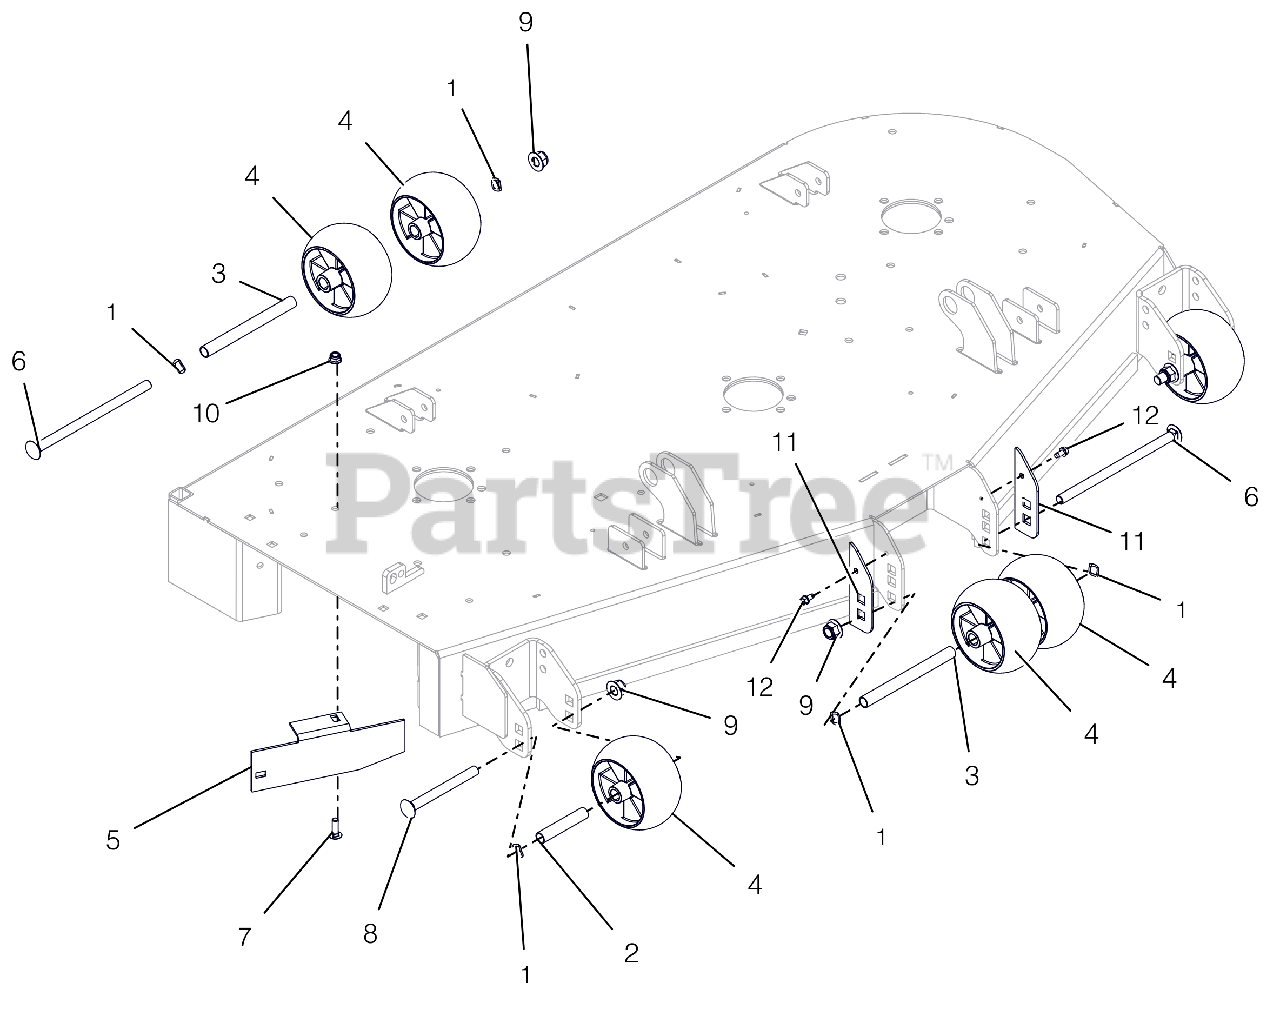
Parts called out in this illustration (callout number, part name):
1	WAVE WASHER .531X.781X.125FH
2	SPACER, .510X.625X3.35
3	SPACER, .510X.625X6.50
4	ANTI-SCALP WHEEL - 5X3 CTR
5	BAFFLE, DISCHARGE, 52"
6	@BLT-RDHDSQNK .50-13X8.50 G5YZ
7	@BLT-RDHDSQNK .31-18X1.00 G5YZ
8	BLT-RDHDSQNK .50-13X5.00 GR5YZ
9	@NUT-LK-NYL-FLG .50-13 YWZC
10	@NUT-LK-NYL-FLG .31-18 YWZC
11	PLATE, ANTI SCALP WHEEL EXT.CE
12	SCR-TAP .25-20X.50 HWH TR YWZ
